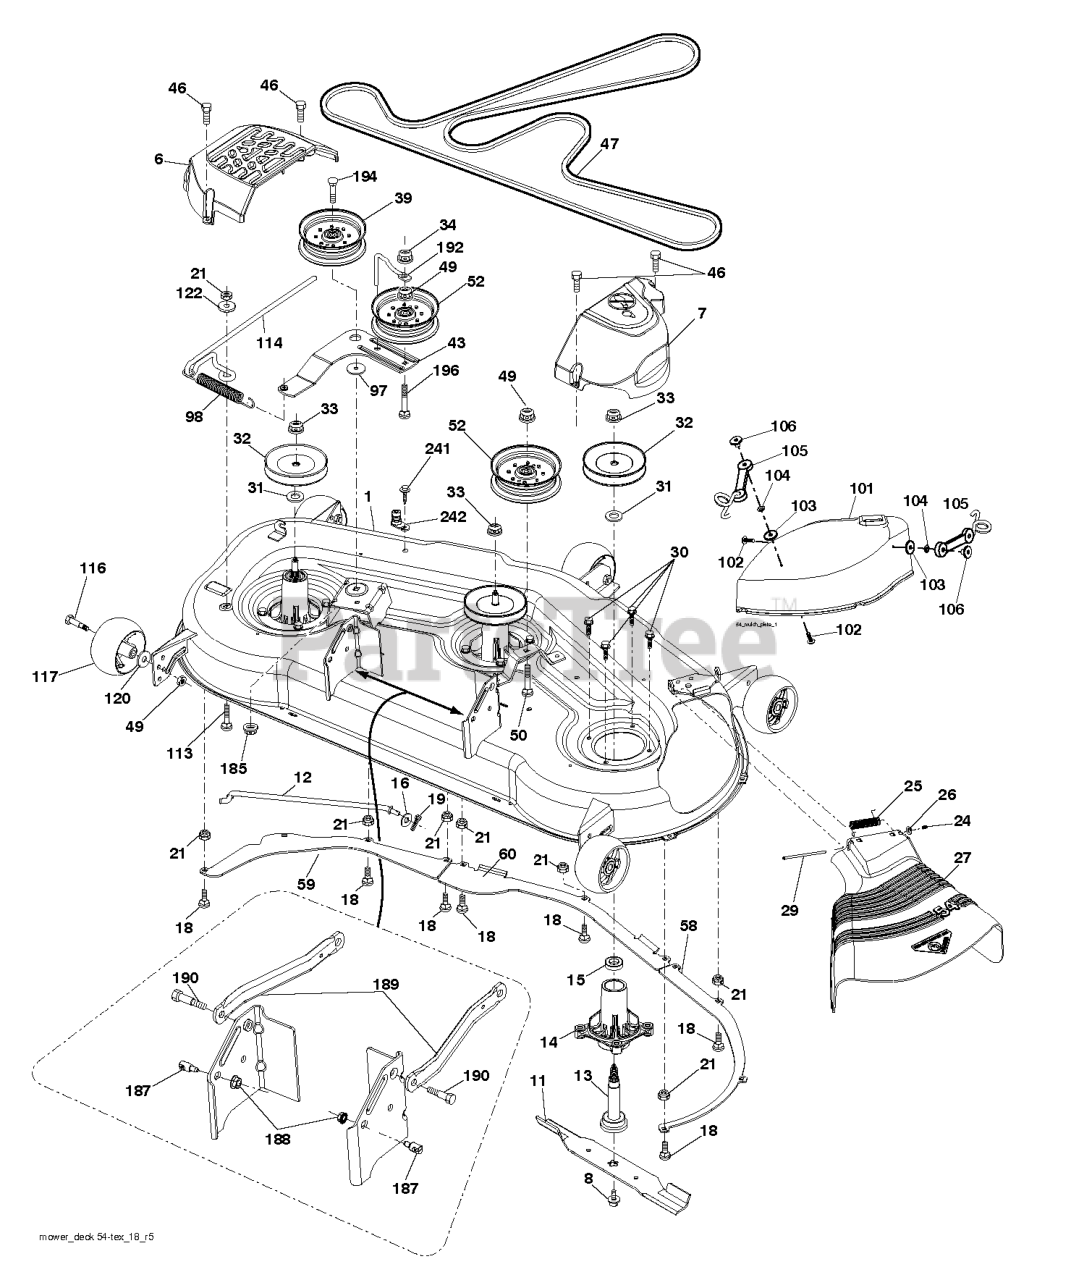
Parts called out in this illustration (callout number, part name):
1	DECK.WELDMENT.54"MS-498
6	COVER.MANDREL.LH.54"20
7	COVER.MANDREL.RH.54.20
8	BOLT.WASHER.ASM.7/16-2
11	54" MULCH BLADE
11	BLADE.BAGGING.54"
12	ROD.ANTI.SWAY.48/54"K4
13	SHAFT ASM MANDREL
14	RP.HOUSING.MANDREL.4PT.
16	WASHER
18	BOLT
19	PIN.COTTER.5/16.BOW TI
21	LOCKNUT
24	CAP-SLEEVE LT
25	SPRING, TORSION
26	NUT PUSH M
27	DEFLECTOR
29	ROD.HINGE
30	SCREW, WASHER HEAD
31	WASHER.SPACER.MANDREL
32	PULLEY/MANDREL
33	NUT.FLANGE.LOCK.TOP
39	RB PULLEY.IDLER.4.50/HUB SPEC
46	SCREW.1/4-20X5/8
47	RP.BELT.DRIVE.54."2006
49	NUT LOCK FLG 3/8-16 UNC
52	PULLEY.IDLER.2006
58	BAFFLE.RIGHT.54"
59	BAFFLE.LEFT.54"
60	BAFFLE CENTER 54" MOWER
98	SPRING, DECK DRIVE
101	MULCH COVER 54"
102	SCREW
104	LOCKWASHER #10
105	LATCH ASSY
106	WELDNUT
114	ROD TENSION RELIEF
116	BOLT.SHOULDER.3/8-16X3-5/8.
117	RP WHEEL. GUAGE RALLY
120	WASHER
122	BUSHING.RELIEF.TENSION
185	NUT.LOCK.FLANGE.7/16
187	STUD.FASTNER.W/ANTI-ROTATE
188	NUT LOCK HEX FLANGE 5/16-18
189	ARM.SUSPENSION.MOWER
190	BOLT.SHOULDER
192	KEEPER.BELT.IDLER.54"T
194	BOLT.HEX.WASHER.HEAD.7/16-24X
241	SCREW.TT.#10-32X.5.3/8.FLANGE
242	PORT.WASHOUT
